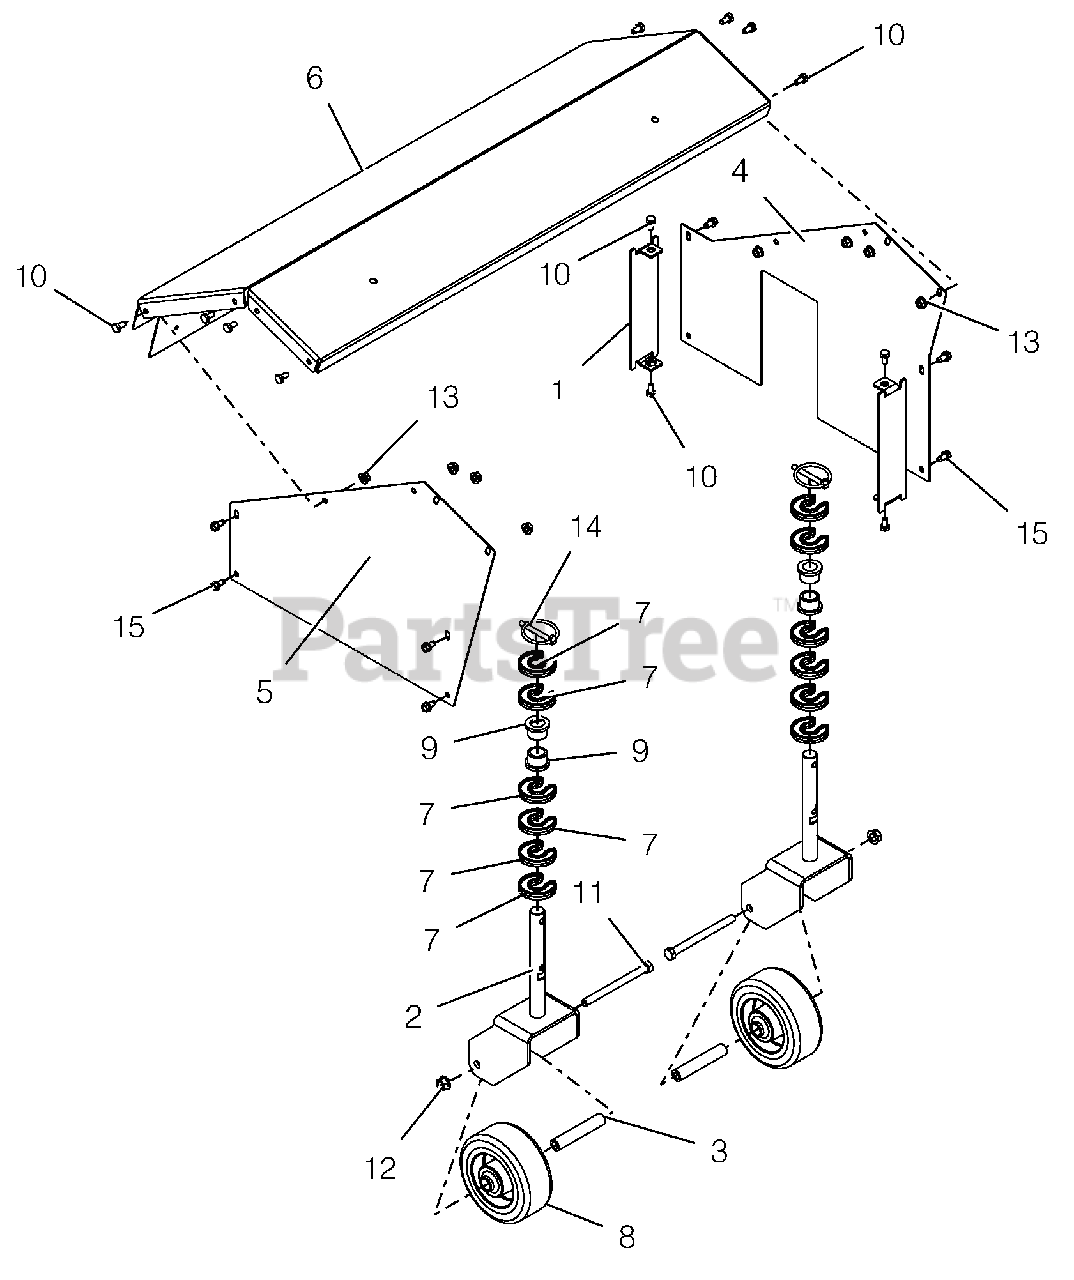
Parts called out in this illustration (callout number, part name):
1	COVER,END
2	FORK, CASTER-BRUSH
3	SPACER, CASTER WHEEL
4	COVER, LH SIDE-BRUSH
5	COVER, RH SIDE-BRUSH
6	COVER, BRUSH-W/DECALS
7	CLIP-HOC FIXED
8	WHEEL, CASTER - 5"OD
9	BUSHING, FLANGE .75X.75X1.0
10	@BLT-HEX .25-20X.50 GR5 YWZC
11	@BLT-HEX .38-16X4.50 GR5 YWZC
12	@NUT-LK-TOP-FLG .38-16 YWZC
13	@NUT-LK-TOP-FLG .25-20 YWZC
14	PIN, LYNCH - .25 X 1.25
15	SCR-TAP .25-20X.50 HWH TR YWZ
